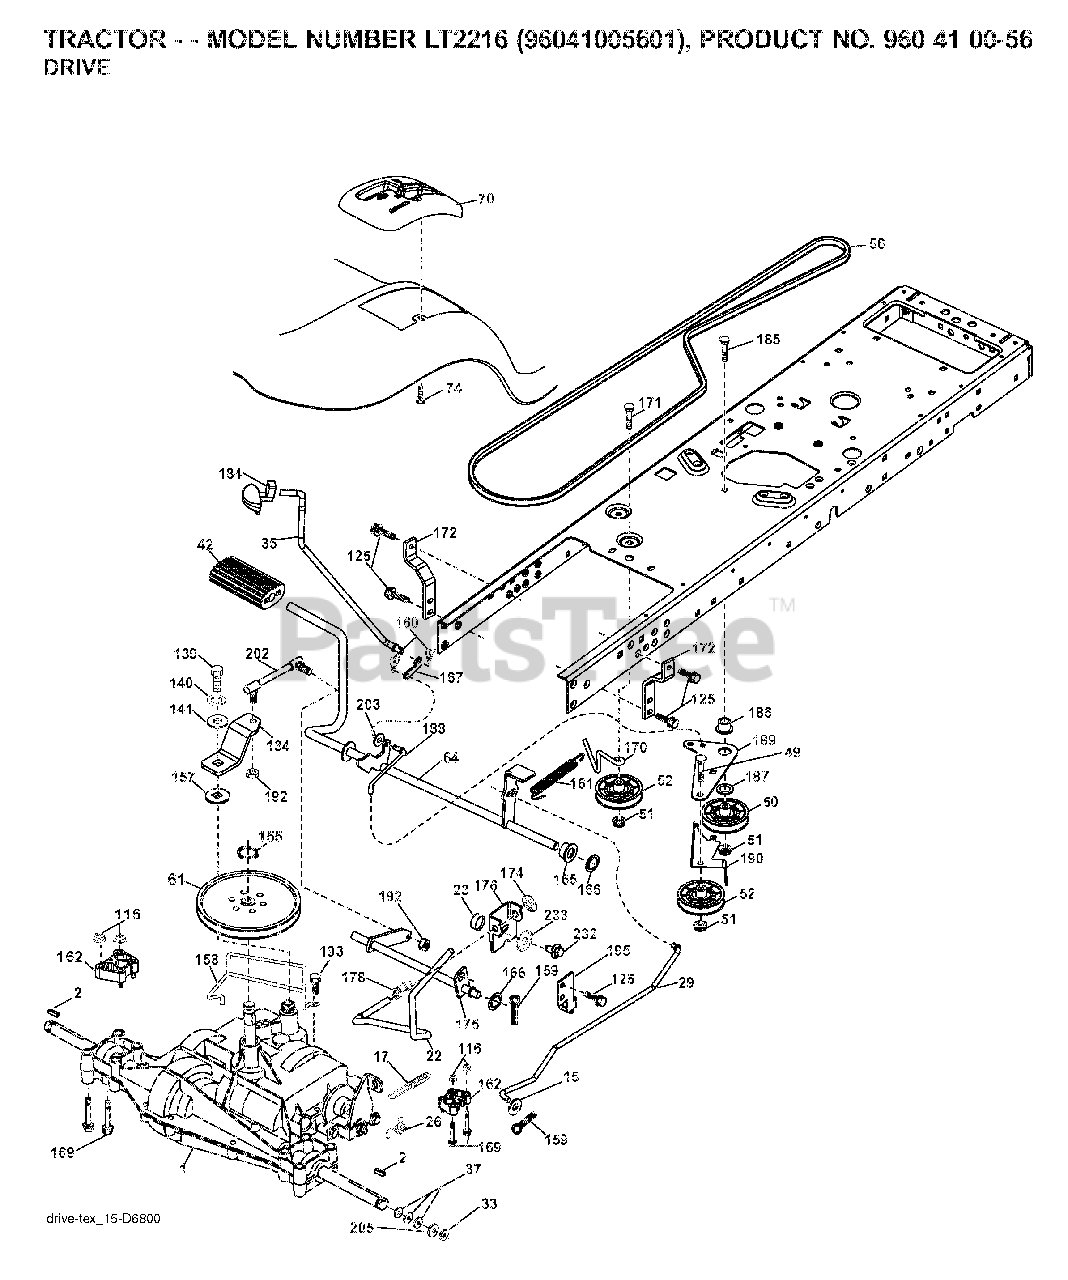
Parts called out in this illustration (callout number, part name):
2	SQUARE KEY
17	SPRING.BRAKE.PEERLESS.TEX
22	ROD.SHIFT.FENDER.TLT.2006
23	KNOB.DUCKHEAD.1/2
26	SPRING.BRAKE.RTN.GR.DR
29	ROD.BRAKE.PEERLESS
33	E-RING LT
35	ROD.BRAKE.PARKING.LT.T
42	PEDAL COVER T
49	BOLT
50	IDLER.FLAT.910.OFFSET
51	NUT LOCK FLG 3/8-16 UNC
52	IDLER.V-GROOVE.910.OFFSET
61	PULLEY TRANS
64	SHAFT.ASM.PEDAL.BRAKE.
70	CONSOLE.SHIFT.
74	SCREW.HI-LO.CONSOLE
116	NUT LOCK HEX FLANGE 5/16-18
125	SCREW
134	ARM.SHIFT.
139	BOLT 1/4-28X3/4
140	LOCKWASHER
141	WASHER LT
155	RETAINING RING LT
157	WASH-SHFT PLT LT
158	KEEPER.PMS.18/20.D4365
159	COTTER PIN
160	RETAINER CLIP
161	SPRING.RETURN.CLUTCH.2006
162	SPACER.TRANSAXLE.18&22
165	BUSHING.SHAFT.BRAKE.HAND
166	NUT.PUSH.625.2006
167	LATCH.BRAKE.SPRING
172	STRAP.TRQ.LH.GEAR.DRIV
174	NUT.PUSH.500.2006
175	SHAFT.ASM.SHIFT.
176	ARM.CLEVIS.ROD.SHIFT
178	SPRING.SHIFT.GT2006
184	HANDLE.PAKRING.BRAKE.
186	SPACER.RETAINER
187	WASHER 12/32X2X10GA
188	LINK.CLUTCH.GROUND.DRIVE
189	BELLCRANK.GROUND.DRIVE.TEX.
190	KEEPER.BELLCRANK.DRIVE
192	NUT LOCK CENTER 1/4 -28 FNTHD
193	SCREW 5/16"
195	BRKT.ROD.BRAKE.PEERLES
202	LINK.TRANSAXLE.
203	WASHER
221	RETAINER.SPRING.CLIP.H
225	BOLT.HEX.FLNG.5/16-18X3.75
232	BOLT FIN HEX 7/16-14 X 1
233	WASHER SERRATED
